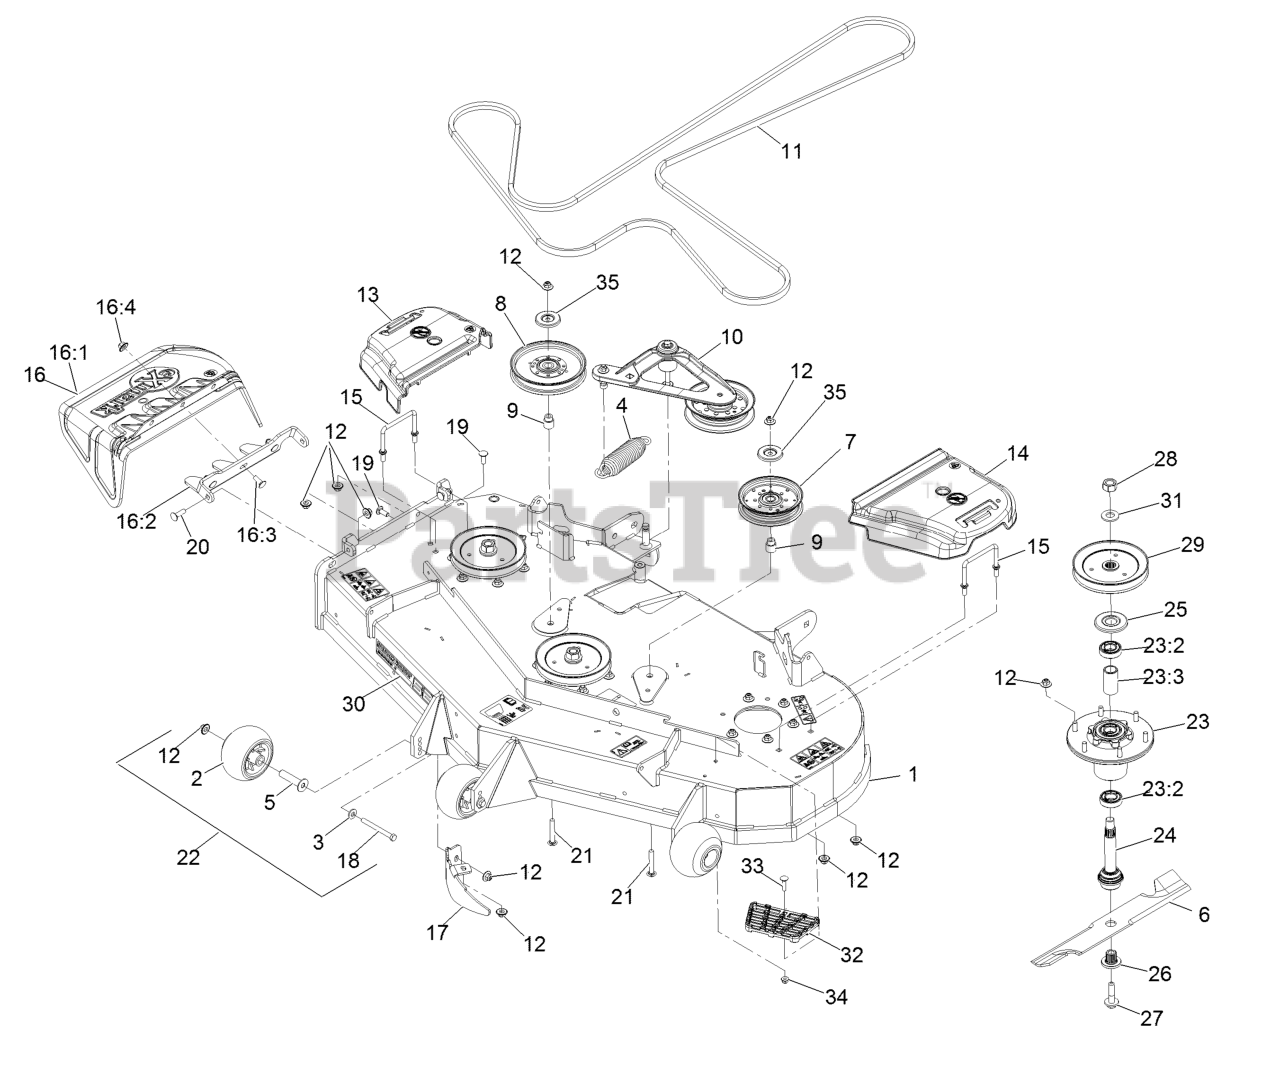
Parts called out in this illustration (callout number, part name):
1	ASM,Deck W/ Decals 52
2	Roller-Anti-Scalp
3	Washer-Spring Disc 3/8
4	Spring-Extension
5	Axle, Roller
6	Blade, Solid
6	Blade, Low Lift
6	Blade, Mulching
6	Blade-Notched
6	Blade-Extreme 2, 18.00"
7	Pulley-Idler, Flat
8	Idler-Pulley
9	Bushing, Idler
10	Deck Idler ASM
11	Belt,V-B X 186.00"
12	Nut-Nyloc 3/8-16 Flg
13	Cover-Belt, RH
14	Cover-Belt, LH
15	Wireform-Cover
16	ASM,Discharge Chute
16:1	Chute, Discharge
16:2	Bracket,Discharge Chute
16:3	Bolt-Carriage 3/8-16 X 1
16:4	Nut-Nyloc 3/8-16 Flg
17	Baffle-Dogleg, Lz-Vt52
18	Screw-HH 3/8-16 X 3 3/4 GR 8
19	Bolt-Carriage 3/8-16 X 1
20	Bolt-Carriage 3/8-16 X 1 1/4
21	Bolt-Carriage 3/8-16 X 2 1/2
22	Kit, Anti-Scalp Roller
23	ASM-Cutter Hsg With Bearings
23:2	Bearing-Ball
23:3	Spacer-Bearing
24	ASM-Spindle And Seal
25	Guard,Bearing Top .989
26	Bushing, Splined
27	Screw-Sems 1/2-20 X 2.19
28	Nut-Hex
29	Sheave,Blade Drive 6.50
30	Decal, 524
31	Washer-Spring Disc 3/4
32	Step-Deck
33	Bolt-Carriage 5/16-18 X 1 1/4
34	Nut-Nyloc 5/16-18 Flg
35	Shield-Dust
